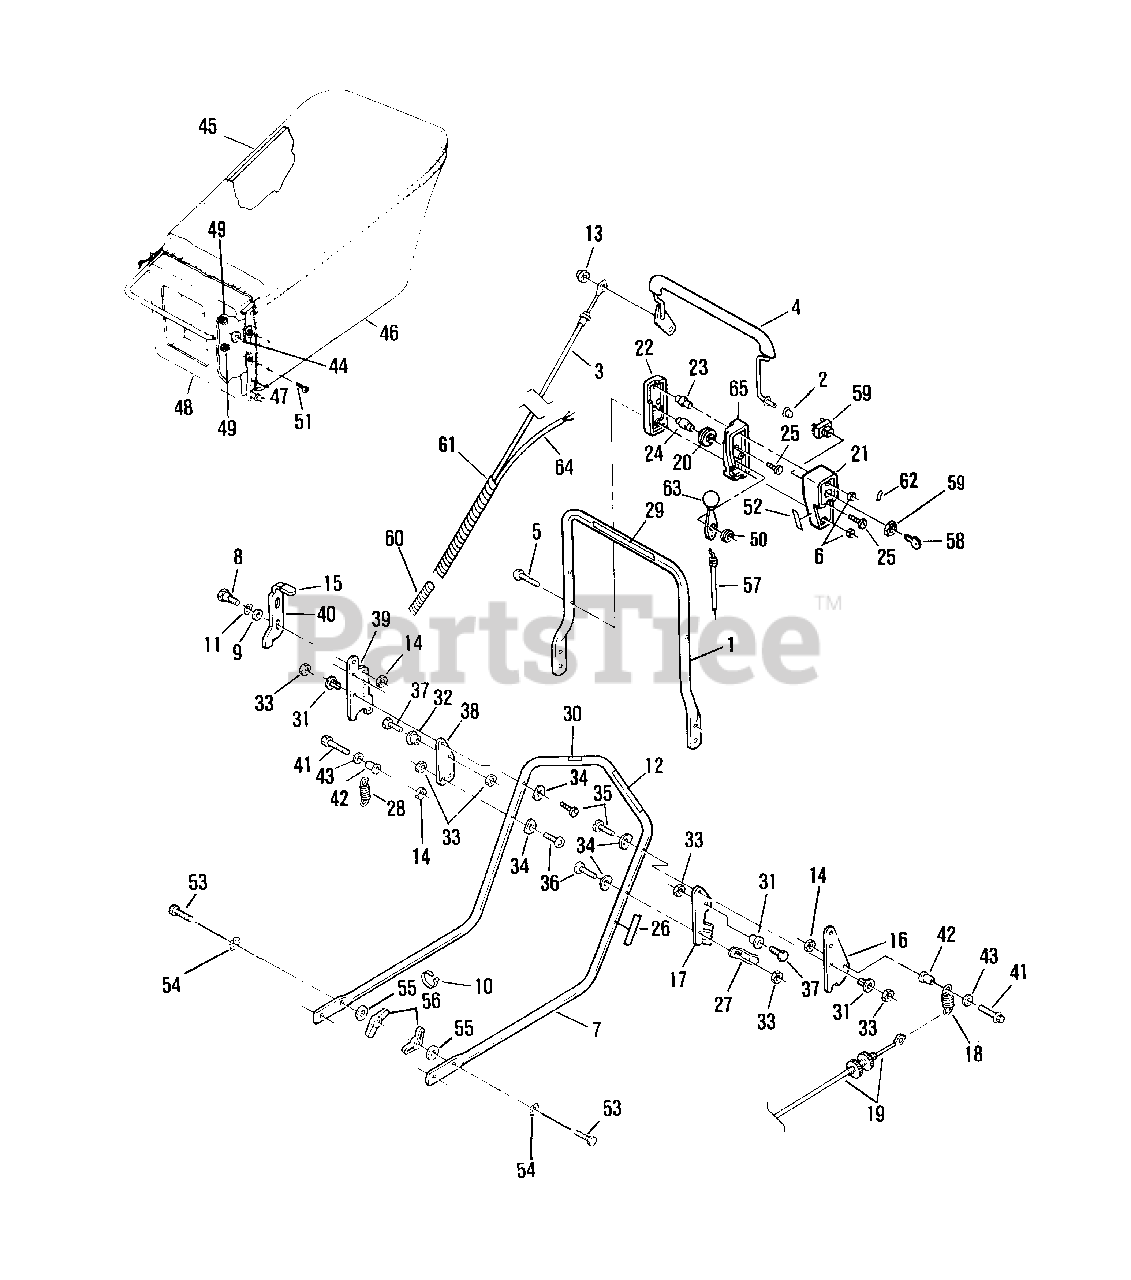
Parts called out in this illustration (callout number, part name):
1	Handle Section-Top
2	Pushnut
3	Control Cable Assembly
4	Control Lever Assembly
5	Truss Head Screw
6	Hex Locknut
7	Handle-Lower
8	Bolt-Shoulder
9	Washer
10	Tie Strap
11	Washer
12	Decal-Starting Instructions
13	Acorn Nut
14	Locknut
15	Knob
16	Plate-Limit
17	Plate-Cable
18	Spring-Cable
19	Cable Assembly
20	Pulley
21	Control Case-Inner
22	Control Case-Outer
23	Column
24	Pin
25	Truss Head Screw
26	Decal-Drive Adjustment
27	Clamp-Cable
28	Spring-Return
29	Decal-Engine/Blade/Drive
30	Decal-Drive Lockout
31	Bushing
32	Bushing
33	Locknut
34	Washer-Curved
35	Truss Head Screw
36	Truss Head Screw
37	Screw
38	Pivot Plate
39	Limit Plate-Right
40	Slide Latch
41	Screw-Truss Head Machine
42	Spacer-Flanged
43	Washer
44	Washer
45	Hanger-Bag
46	Grass Bag Assembly
47	Latch Bar Assembly
48	Bag Adapter
49	Nut-Bag Adapter
50	Washer-Spring
51	Screw-Bar Adapter
52	Decal-Throttle Control
53	Screw
54	Lockwasher
55	Washer
56	Wing Nut
57	Cable-Throttle
58	Key (Two)
59	Key Switch
60	Spiral Tubing
61	Spiral Tubing-17.5"
62	Decal-Start
63	Lever and Knob Assembly
64	Wire Harness
65	Control Case-Center
